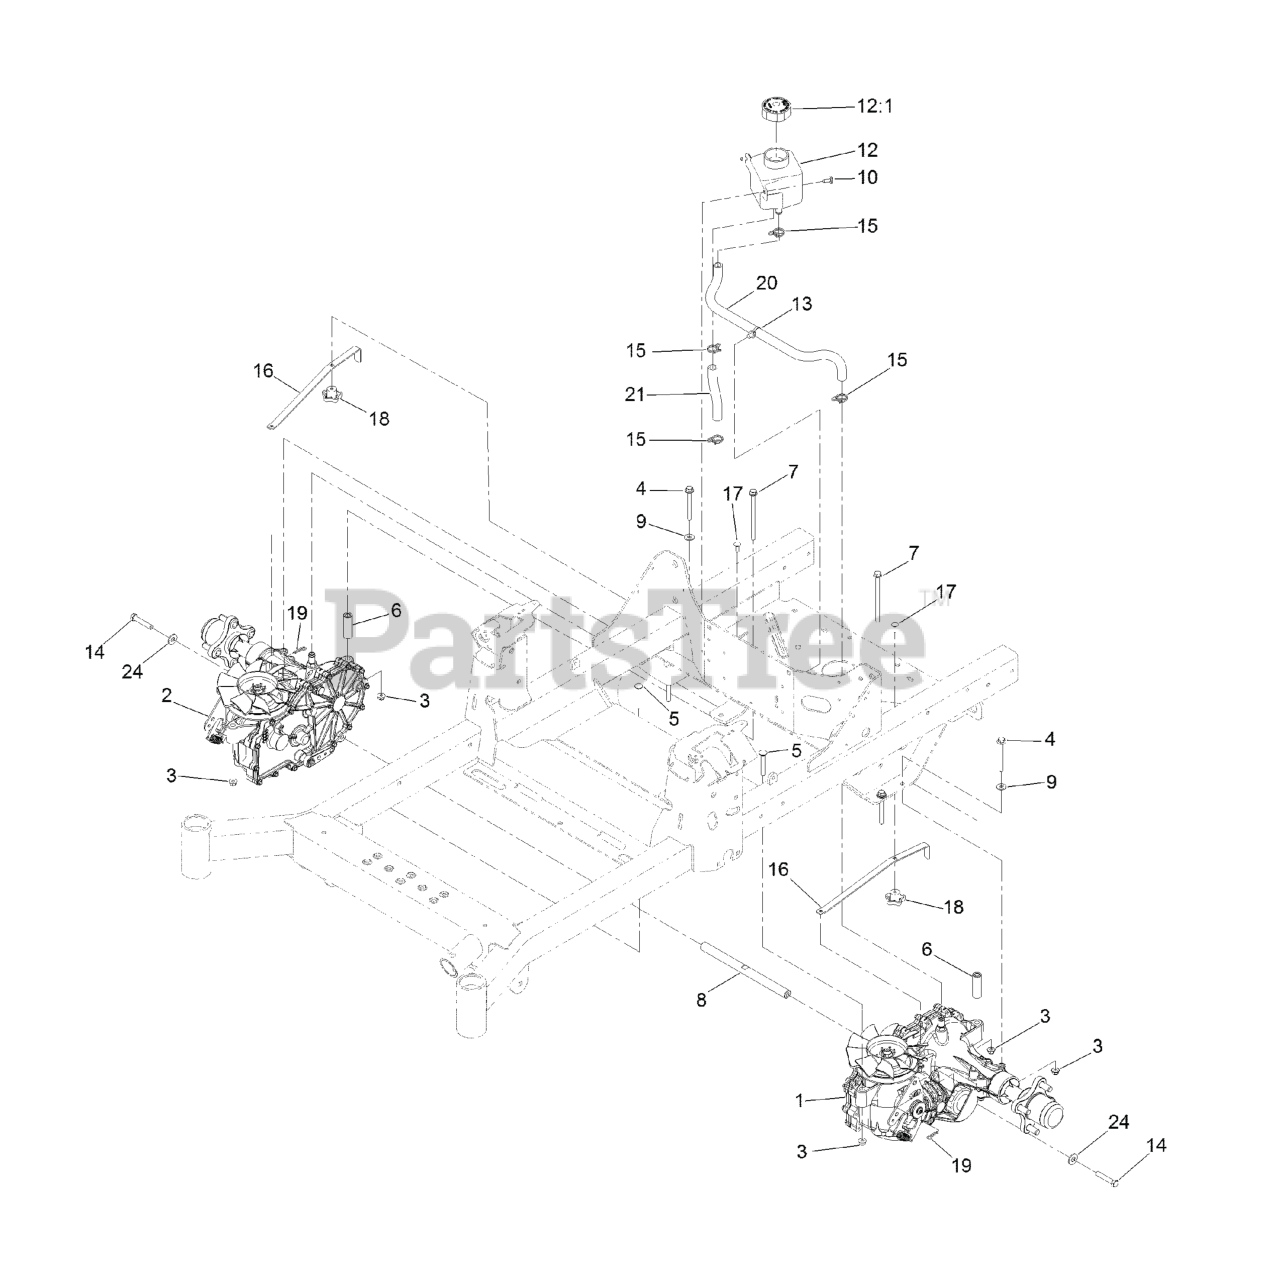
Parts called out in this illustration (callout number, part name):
1	LH TRANSAXLE ASM
2	RH TRANSAXLE ASM
3	NUT-HF, NI
4	SCREW-HHF
5	BOLT-CARR
6	SPACER-HYDRO
7	SCREW HHF
8	SHAFT-SPACER
9	WASHER-SPRING
10	SCREW-TORX
12	TANK-HYD
12:1	CAP-RESERVOIR, HYD
13	CLIP-TIE
14	SCREW-HH W/LOCTITE
15	CLAMP-HOSE
16	ARM-BYPASS, HYDRO
17	BOLT-CARR
18	KNOB-HANDLE
19	PIN-COTTER
20	HOSE-HYDRAULIC
21	HOSE-HYDRAULIC
24	WASHER-FLAT
